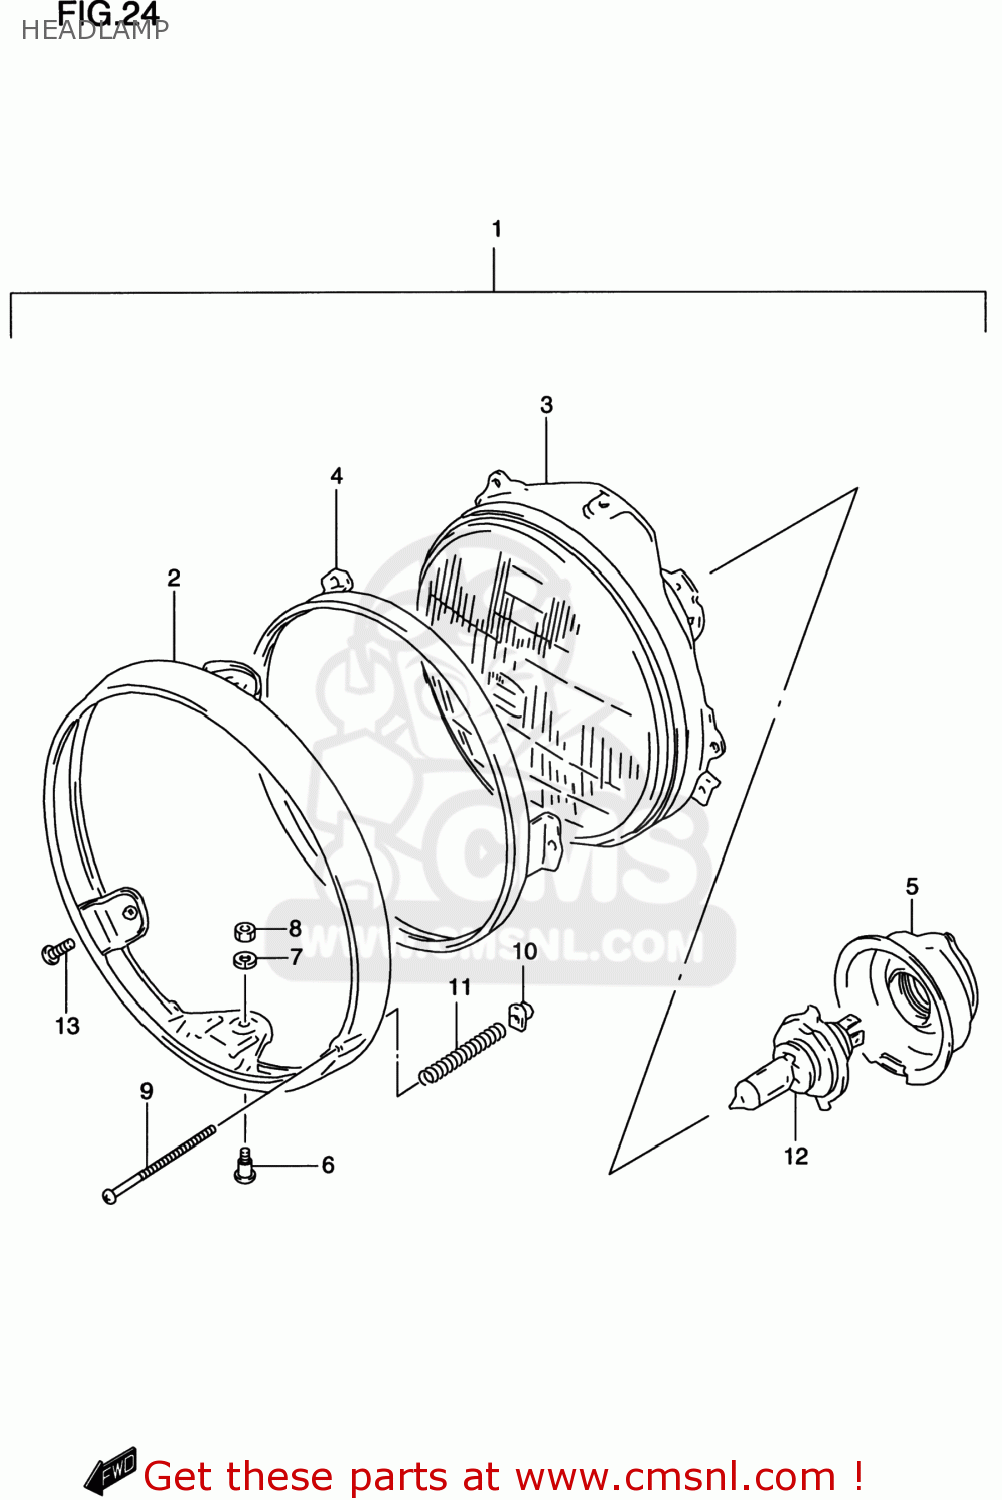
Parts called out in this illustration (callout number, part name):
1	HEADLAMP ASSY
2	RIM,HEADLAMP
3	LAMP UNIT
4	RING
5	COVER,SOCKET
6	H/LAMP LENS UNIT FITING SCRE
7	WASHER,LOCK
8	NUT
9	SCREW
10	NUT
11	SPRING,ADJUSTING
12	BULB(12V60/55W,H4)
13	SCREW
